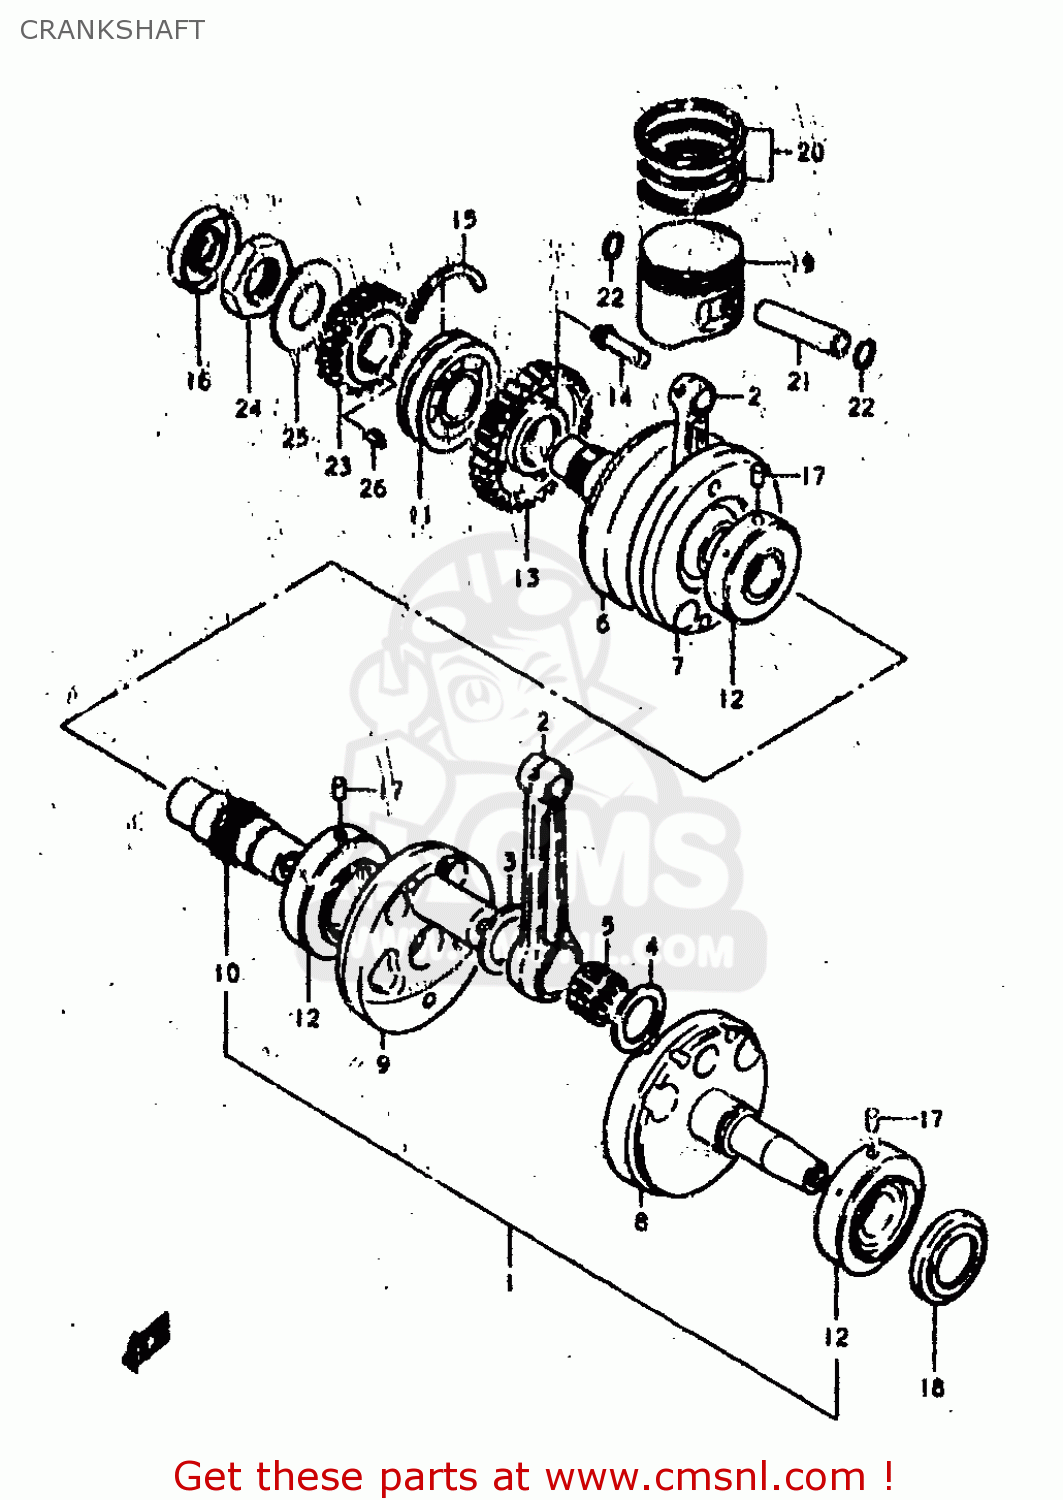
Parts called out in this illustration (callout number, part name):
1	CRANKSHAFT ASSEMBLY
2	ROD,CONNECTING
3	WASHER (28X48X2)
4	WASHER(28X48X1)
5	BEARING(28X38X19.8)
6	CRANKSHAFT
7	WEB,CRANK
8	CRANKSHAFT,LEFT
9	WEB,CRANK
10	SHAFT,TIMING CHAIN DRIVE
11	BEARING(30X72X19)
12	BEARING
13	GEAR,CRANK BALANCER DRIVE
14	PIN
15	C RING
16	SEAL,OIL(25X47X8)
17	PIN
18	OIL SEAL
19	PISTON
20	PISTON RING SET
21	PIN,PISTON
22	CIRCLIP
23	GEAR,PRIMARY DRIVE
24	NUT
25	WASHER
26	KEY
